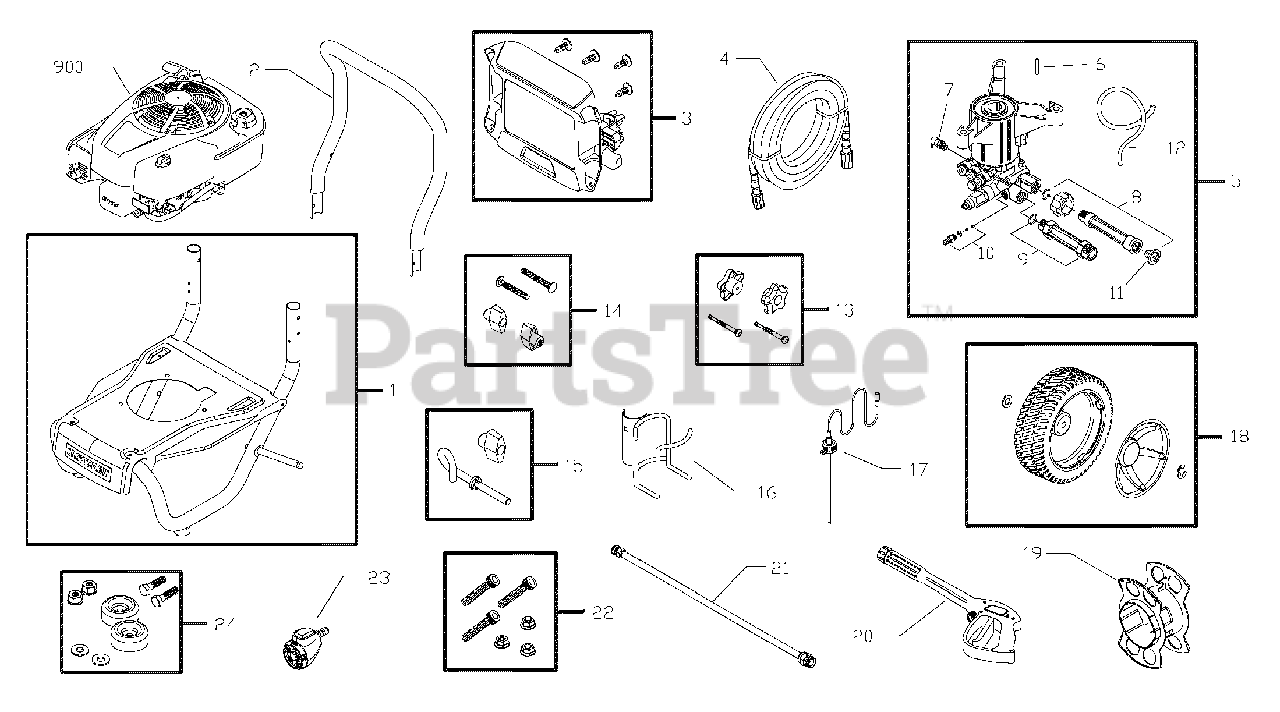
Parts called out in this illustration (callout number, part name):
1	BASE
4	HOSE
5	PUMP
7	VALVE, Thermo Relief
8	KIT, Water Inlet
10	KIT, Chemical Injection
11	FILTER, Garden Hose
12	HOSE, Chemical
13	KIT, Hardware, Handle
14	KIT, Hardware, Handle
20	GUN
21	EXTENSION, QC
22	KIT, Hardware, Pump Mounting
23	NOZZLE, QC
24	MOUNT, Vibration
